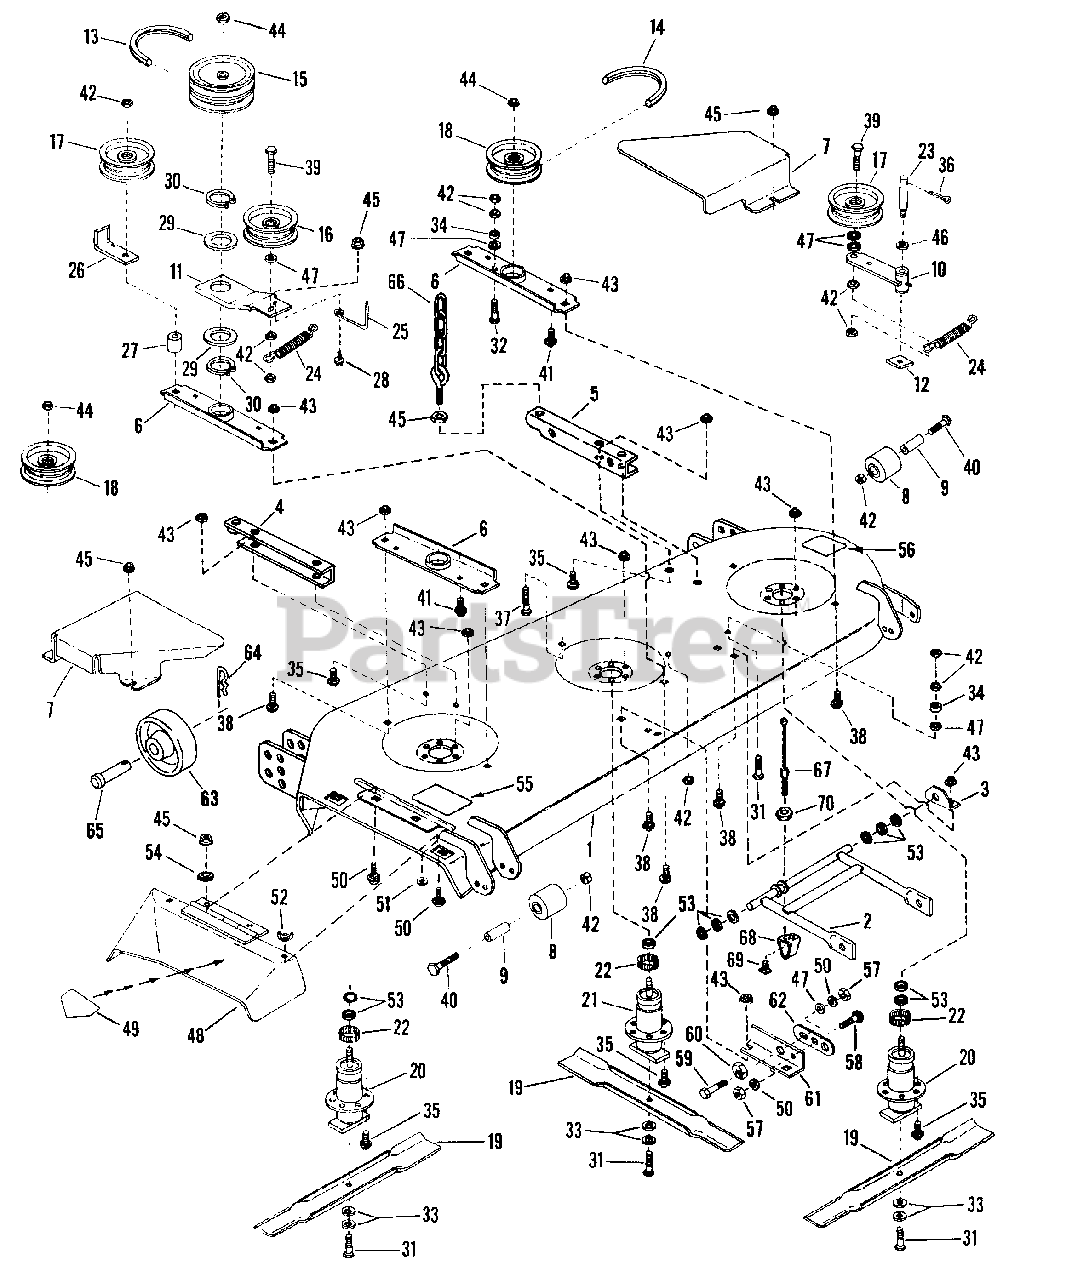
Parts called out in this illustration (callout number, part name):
1	DECK STRUCTURE - 48"
2	ARM, Front Lift
3	BRACKET, Front Hanger
4	SUPPORT, Rear Right (1985)
5	SUPPORT, Rear Left (1985)
6	BRACE, Spindle
7	GUARD, Pulley
8	ROLLER
9	SPACE
10	ASSEMBLY, Idler Arm
11	IDLER ARM, Center
12	WASHER - Square
13	V-BELT, Drive - A92
14	BELT, Deck - AA105
15	PULLEY, Double (4-3/4")
16	PULLEY, Flat Idler (4.8 O.D.)
17	PULLEY, V-Idler (4-1/2" O.D.)
18	PULLEY, 4-3/4" O.D.
19	BLADE, 16.5
20	ASSEMBLY, Spindle
21	ASSEMBLY, Spindle
22	TOLERANCE RING, 3/4"
23	IDLER STUD
24	SPRING
25	BELT GUIDE
26	BELT GUIDE
28	BOLT, 5/16-18 x 3/4" Short Square Neck, Grade 5
29	WASHER, Plastic
30	RING, 2" External Retaining
31	SCREW, 3/8-24 x 1-1/4" Hex Head Cap, Grade 5
32	SCREW, 3/8-24 x 1-1/2" Hex Head Cap, Grade 2
33	WASHER, Cone
34	SPACER
35	BOLT, 3/8-16 x 3/4" Hex Flange Lock
36	PIN, 1/8 x 1" Cotter
37	SCREW, 3/8-24 x 2-1/2" Hex Head Cap
38	BOLT, 3/8-16 x 3/4" Square Neck Carriage, Grade 2
39	SCREW, 3/8-24 x 2" Hex Head Cap, Grade 5
40	SCREW, 3/8-24 x 3-3/4" Hex Head Cap, Grade 5
41	BOLT, 5/16-18 x 5/8" Square Neck Carriage, Grade 5
42	NUT, 3/8-24 Hex Ctr. Lock
43	NUT, 3/8-16 Hex Fl. Lock
44	NUT, 3/4-16 Lock
45	NUT, 5/16-18 Hex Fl. Lock
46	WASHER, 5/8 SAE
47	WASHER, 3/8 SAE
48	ASSEMBLY, Side Chute
49	DECAL, Danger
50	WASHER, 3/8 Split Lock
51	WASHER, 5/16 Split Lock
52	WING-NUT, 5/16-18
53	WASHER, 3/4 I.D.
54	RETAINER, 5/16 Bolt
55	DECAL, Caution
56	DECAL, Caution
57	NUT, 3/8-16 Hex
58	BOLT, 3/8-16 x 3/4" Short Square Neck Carr., Gr. 2
59	SCREW, 3/8-16 x 1" Hex Head Cap, Grade 5
60	RING, Adjustment
61	BRACKET, Right Front
62	LINK, Adjustment
63	WHEEL, 6.00" Gage
64	PIN, Hair Cotter
65	PIN, 1/2 x 3" Clevis
66	ASSEMBLY, Bolt/Chain
67	CABLE, Front Lift (8")
68	BRACKET, Front Lift Hanger
69	T-NUT, 5/16-18
70	NUT, 3/8-16 Hex Jam
